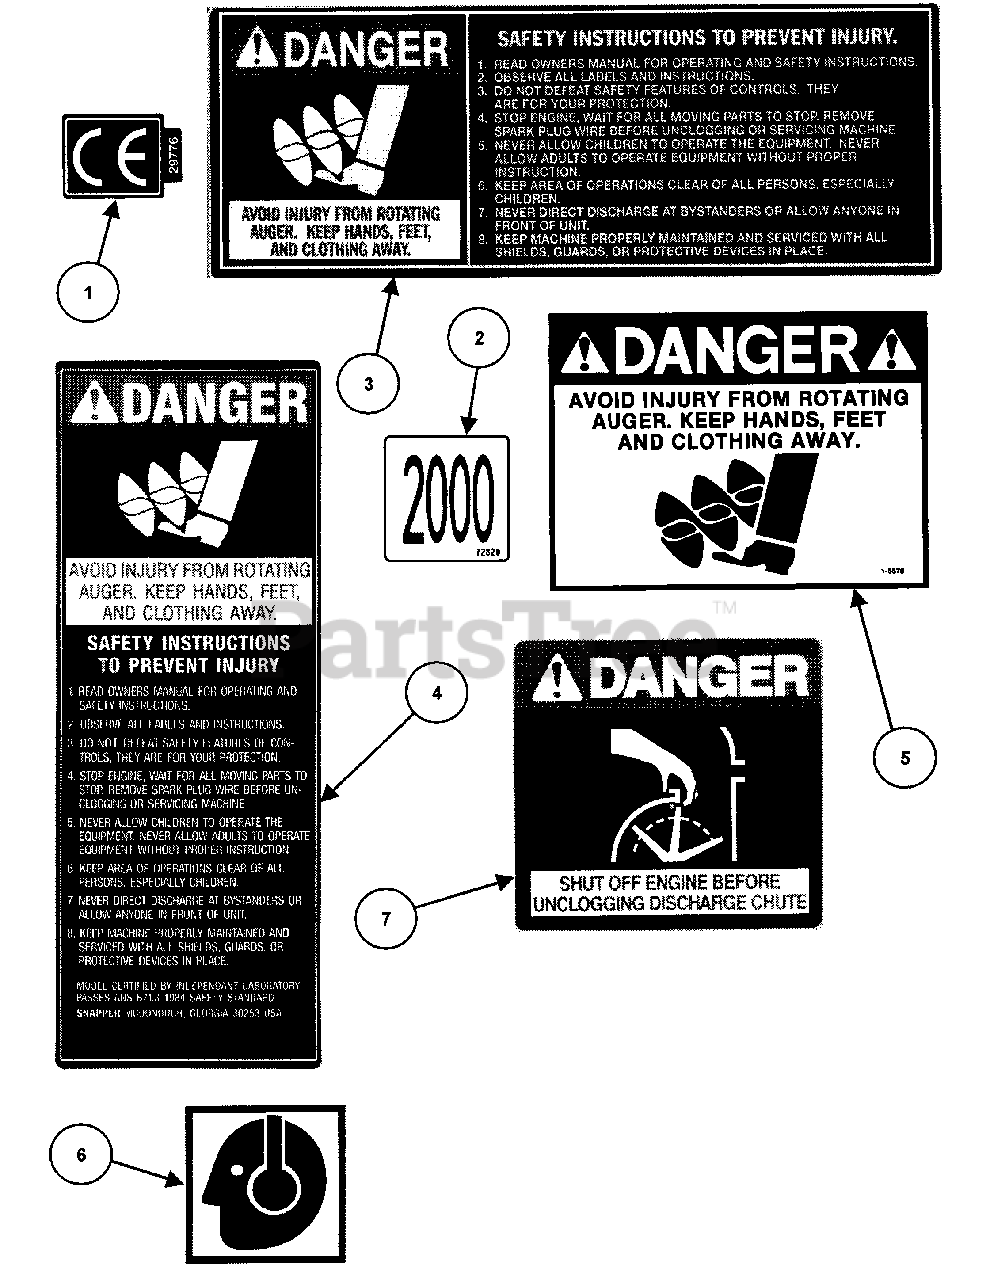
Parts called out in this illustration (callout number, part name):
1	DECAL, European Community (CE)
2	DECAL, 2000 Year of Manufacture
3	DECAL, Foot Danger/Blank
4	DECAL, Foot Danger/Blank
5	DECAL, Danger (Collector)
6	DECAL, Ear Protection
7	DECAL, Hand Danger
